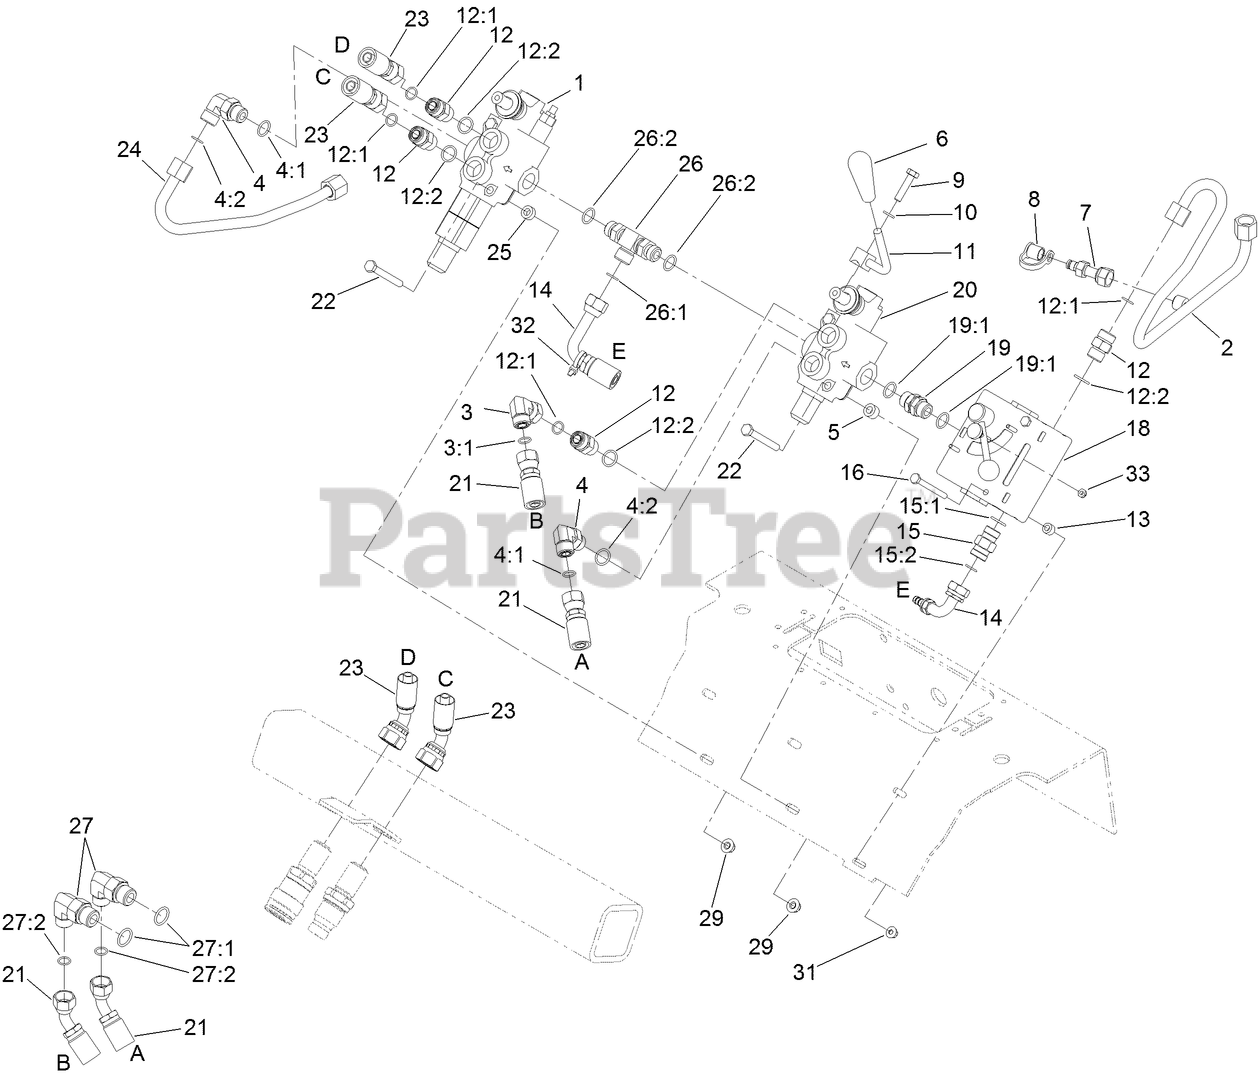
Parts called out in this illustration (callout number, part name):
1	VALVE-HYD, AUXILIARY
2	TUBE-HYD
3	FITTING-HYD
3:1	O-RING
4	FITTING-ELBOW, 90 DEG
4:1	O-RING
4:2	O-RING
5	SPACER
6	KNOB-TAPERED
7	NIPPLE-TEST
8	CAP-DUST
9	SCREW-HH
10	WASHER-LOCK
11	LEVER-CONTROL
12	FITTING-STRAIGHT
12:1	O-RING
12:2	O-RING
13	SPACER
14	HOSE-HYD
15	VALVE-CHECK, HYD
15:1	O-RING
15:2	O-RING
16	SCREW-HH
18	HYD VALVE KIT
19	FITTING-THREAD, STRAIGHT
19:1	O-RING
20	VALVE-SELECTOR, HYD
21	HOSE-PUMP, HYD
22	SCREW-HH
23	HOSE-HYD
24	TUBE-HYD
25	SPACER
26	ADAPTER-TEE, ADJUSTABLE
26:1	O-RING
26:2	O-RING
27	FITTING-ELBOW, 90 DEG
27:1	O-RING
27:2	O-RING
29	NUT-HF, NI
31	NUT-FLANGE, NI
32	TIE-CABLE
33	NUT-LOCK, NI
